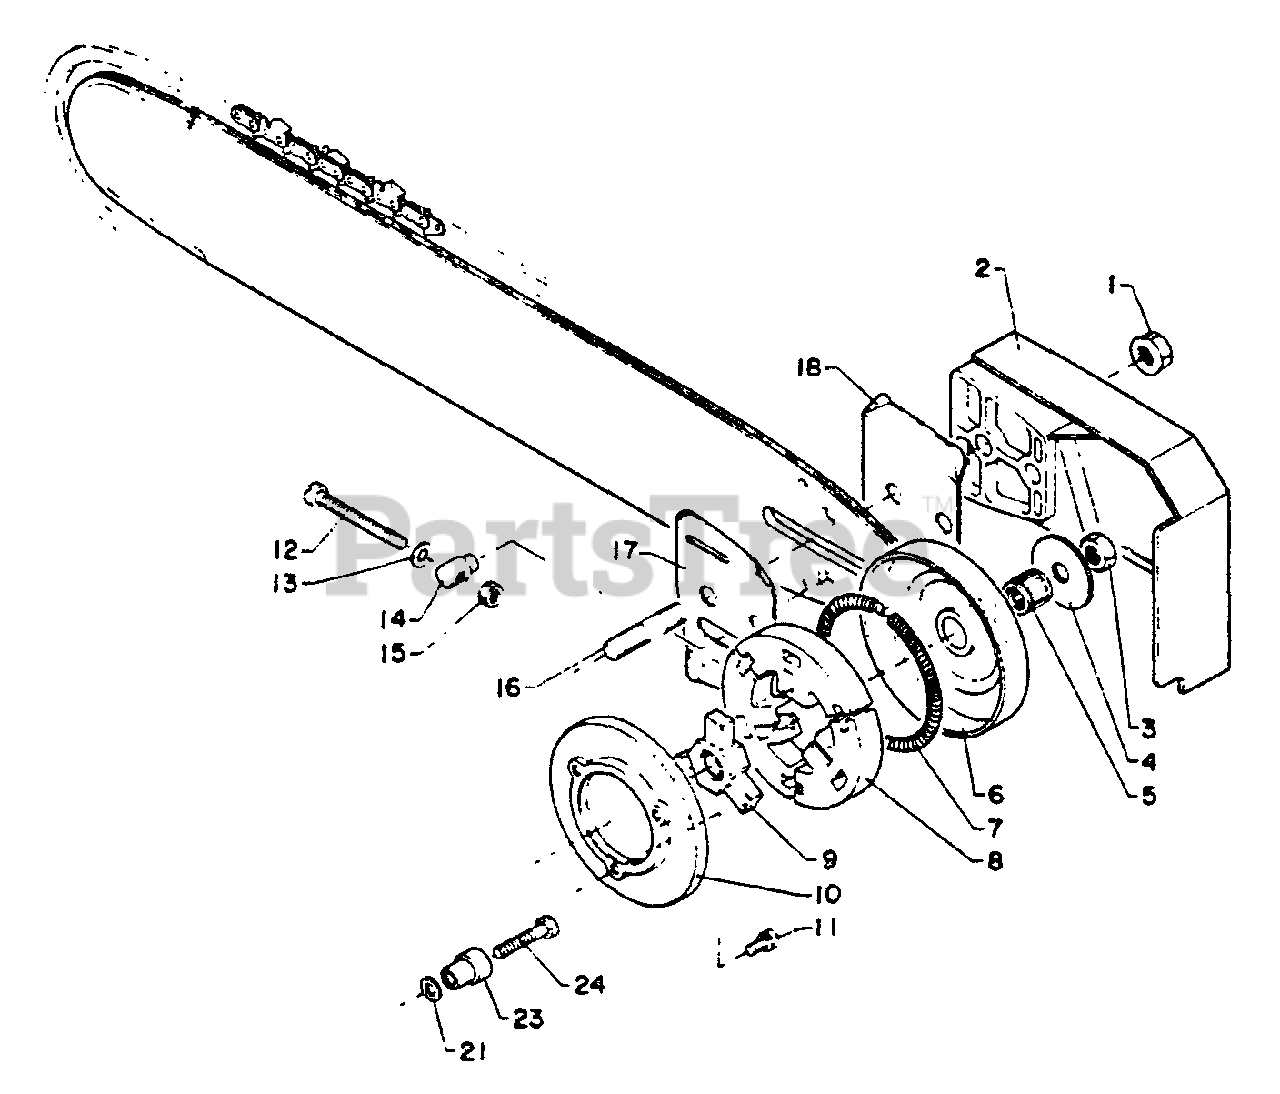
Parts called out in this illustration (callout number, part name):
1	NUT, FLANGE M8×1.25
2	GUARD, SPROCKET
3	LOCKNUT
4	WASHER, CLUTCH
5	BEARING, NEEDLE
6	DRUM, CLUTCH - 3/8"
7	SPRING, CLUTCH
8	SHOE, CLUTCH
9	HUB, CLUTCH
10	SEAL, DUST
11	SCREW 4×10
12	SCREW, ADJUSTER
13	WASHER
14	TENSIONER, CHAIN
15	LOCKNUT - 5
16	STUD, GUIDE BAR
17	PLATE, GUIDE - INNER
18	PLATE, GUIDE - OUTER
21	WASHER, FLAT 5.5×10×0.8
23	CATCHER, CHAIN
24	SCREW 5×25
